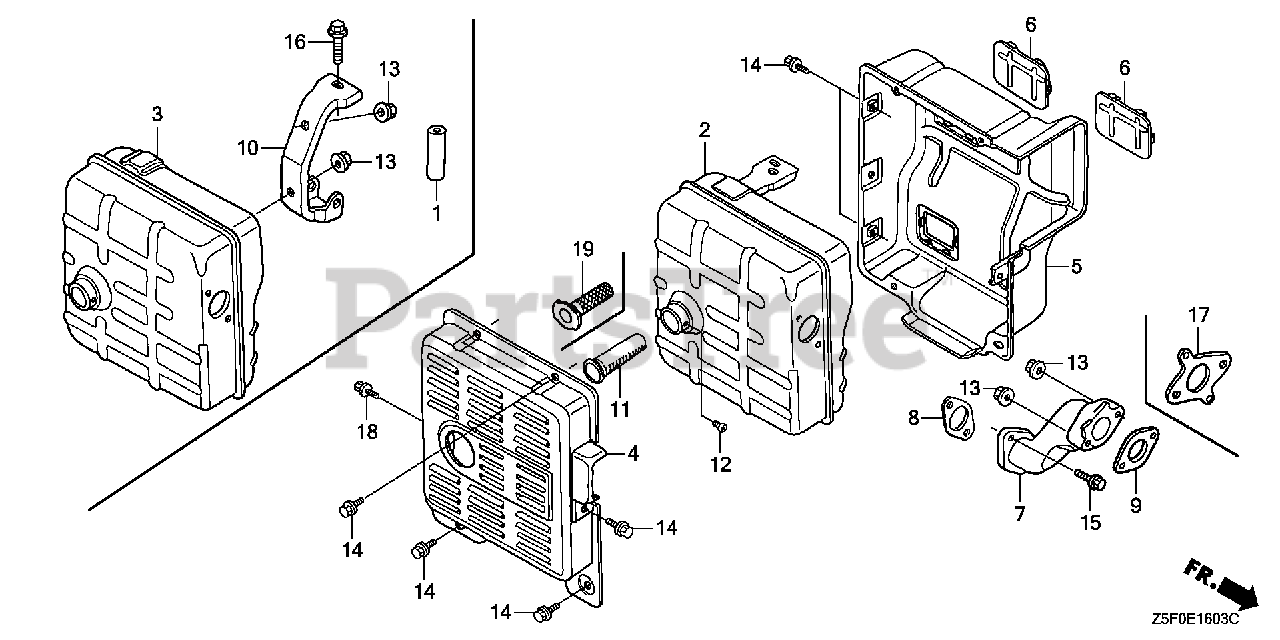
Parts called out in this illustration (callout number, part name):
2	MUFFLER (DENYO)
4	PROTECTOR, MUFFLER (OUTER)
5	PROTECTOR, MUFFLER (INNER)
6	SEAL, MUFFLER PROTECTOR
8	GASKET, EX. PIPE
11	ARRESTER, SPARK
12	SCREW, TAPPING (4X8)
13	NUT, FLANGE (8MM)
14	BOLT, FLANGE (6X12) Use up to Engine SN 1543277.
15	BOLT, FLANGE (8X20) Use up to Engine SN 1609606.
17	GASKET, EX. PIPE
18	BOLT, FLANGE (6X12) Use up to Engine SN 1543277.
19	ARRESTER, SPARK
